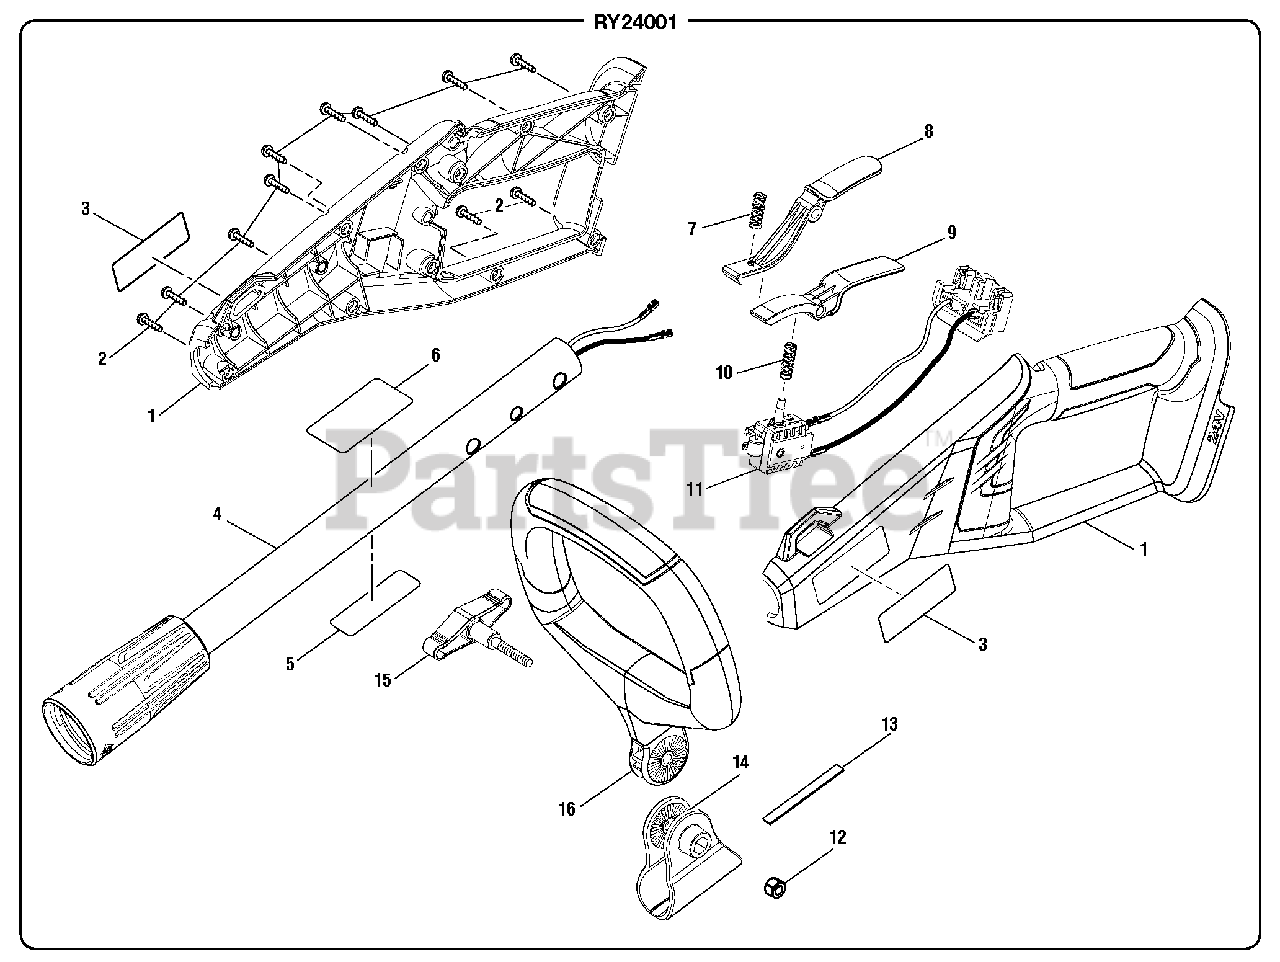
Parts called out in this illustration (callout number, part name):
1	Rear Handle Assembly
2	Screw (M4 x 14 mm, T15 Torx Pan Hd.)
3	Logo Label
4	Upper Tube Assembly
5	Data Label
6	Waning Icon Label
7	Compression Spring (Trigger Lock)
8	Trigger Lock
9	Switch Trigger
10	Compression Spring (Trigger)
11	Switch and Contact Plate Assembly
12	Hex Nut (M6)
13	Handle Bracket Spacer
14	Handle Bracket
15	Handle Knob Assembly
16	Auxiliary Handle Assembly
